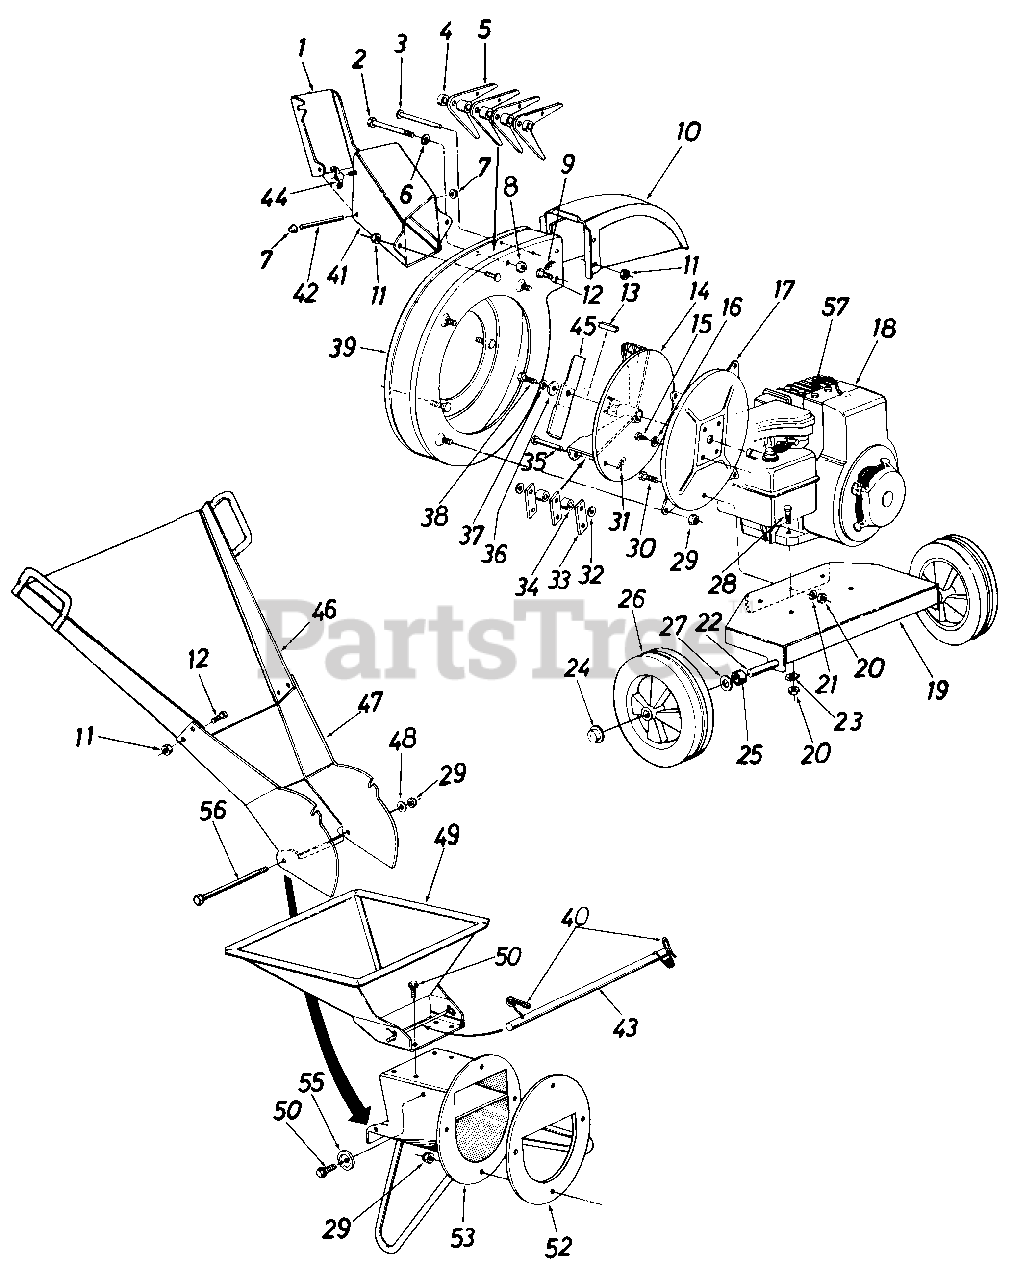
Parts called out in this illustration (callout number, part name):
1	Door Chip It
2	Hex Bolt 1/2-20 x 4.50" Lg.*
3	Clevis Pin
4	Flail Spacer 7/32" Lg.
5	Cutting Finger
6	L-Wash. 1/2" I.D.*
7	Palnut 3/16" Dia.
8	Hex Jam Nut 1/2-20 Thd.*
9	Cotter Pin 3/32" Dia. x 3/4" Lg.
10	Chute Deflector
11	L.-Nut 1/4-20 Thd.
12	Hex Bolt 1/4-20 x .50" Lg.*
13	Sq. Key 1/4" x 2.00" Lg.
14	Impeller Assembly
15	Hex Bolt 5/16-24 x 3/4" Lg.
16	L.-Wash. 5/16" I.D.*
17	Hopper to Engine Mtg. Plate
18	Engine
19	Engine Mounting Plate
20	Hex Nut 5/16-24 Thd.*
21	L.-Wash. 5/16" I.D.*
22	Shaft
23	Special L.-Wash. 5/16" I.D.
24	Push Cap
25	Spacer
26	Wheel Ass'y.-Comp.
27	Fl.-Wash. .50" I.D.
28	Hex Bolt 5/16-24 x 1.50" Lg.*
29	Elastic Lock Nut 5/16-18 Thd.
30	Hex Bolt 5/16-24 x .62" Lg.*
31	Cotter Pin 1/8" Dia. x 1.00" Lg.*
32	Fl.-Wash. .531" I.D. x 937 0 O.D. x .09
33	Flail
34	Flail Spacer 23/32" Lg.
35	Clevis Pin .50" Dia. x 3.0" Lg.
36	Fl.-Wash. .406" I.D. x 1.25" O.D. Hdn.
37	L.-Wash. 3/8" I.D. H.D.
38	Hex Bolt 3/8-24 x 2.0" Lg. H.T.
41	Chip-lt Guide Ass'y.
42	Hinge Pin
43	Release Bar
44	Wing Nut Elastic 1/4-20 Thd.
46	Upper Leaf Ramp Section
47	Lower Leaf Ramp Section
48	Fl.-Wash. 5/16" I.D.
49	Hopper Assembly
50	Hex Wash. Hd. Self-Tap Scr. 5/16-18 x .75" Lg.
52	Back-Up Plate
53	Inlet Guide Assembly
55	Stop Washer
56	Hex Bolt 5/16-18 x 8.38" Lg.
57	Spark Plug Elbow
